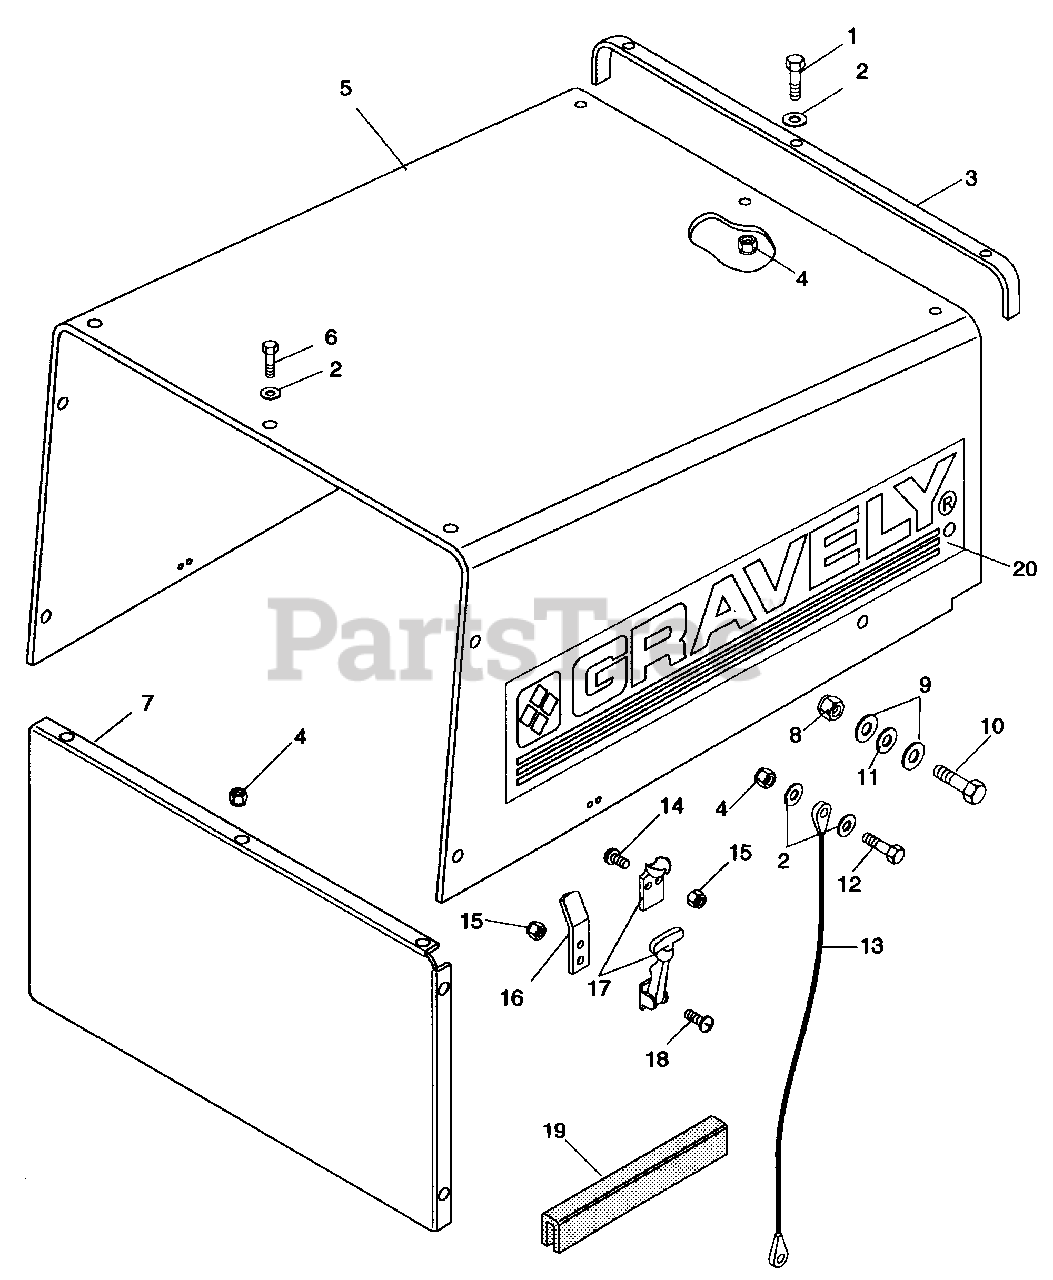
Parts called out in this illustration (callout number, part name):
1	BLT-HEX .25-20 X .75 PL GR 5
2	WSHR-FL-STL .281 X .625 X .065
3	BRACE, HOOD
4	NUT-LK-NYL .250-20 PL
5	HOOD
6	BLT-HEX .25-20 X .63
7	PANEL, HOOD
8	NUT-LK-NYL .375-16 PL
9	WSHR-FL-STL .406 X .812 X .065
10	BLT-HEX .380-16 X .875
11	WSHR-FL-NY .375 X .75 X .060
12	BLT-HEX .25-20 X .875
13	CBL, HOOD
14	SCR-MCH 10-24 X .50 PHD
15	NUT-LK 10-24 NY PL
16	PLT, GUIDE
17	LATCH
18	SCR-MCH 10-24 X .750 PHD
19	STRIP, COWL
20	GRAVELY NAME/LOGO/STRIPE DECAL
NS	DECAL, E-SYSTEM WARNING
NS	DECAL, MAINTENANCE
